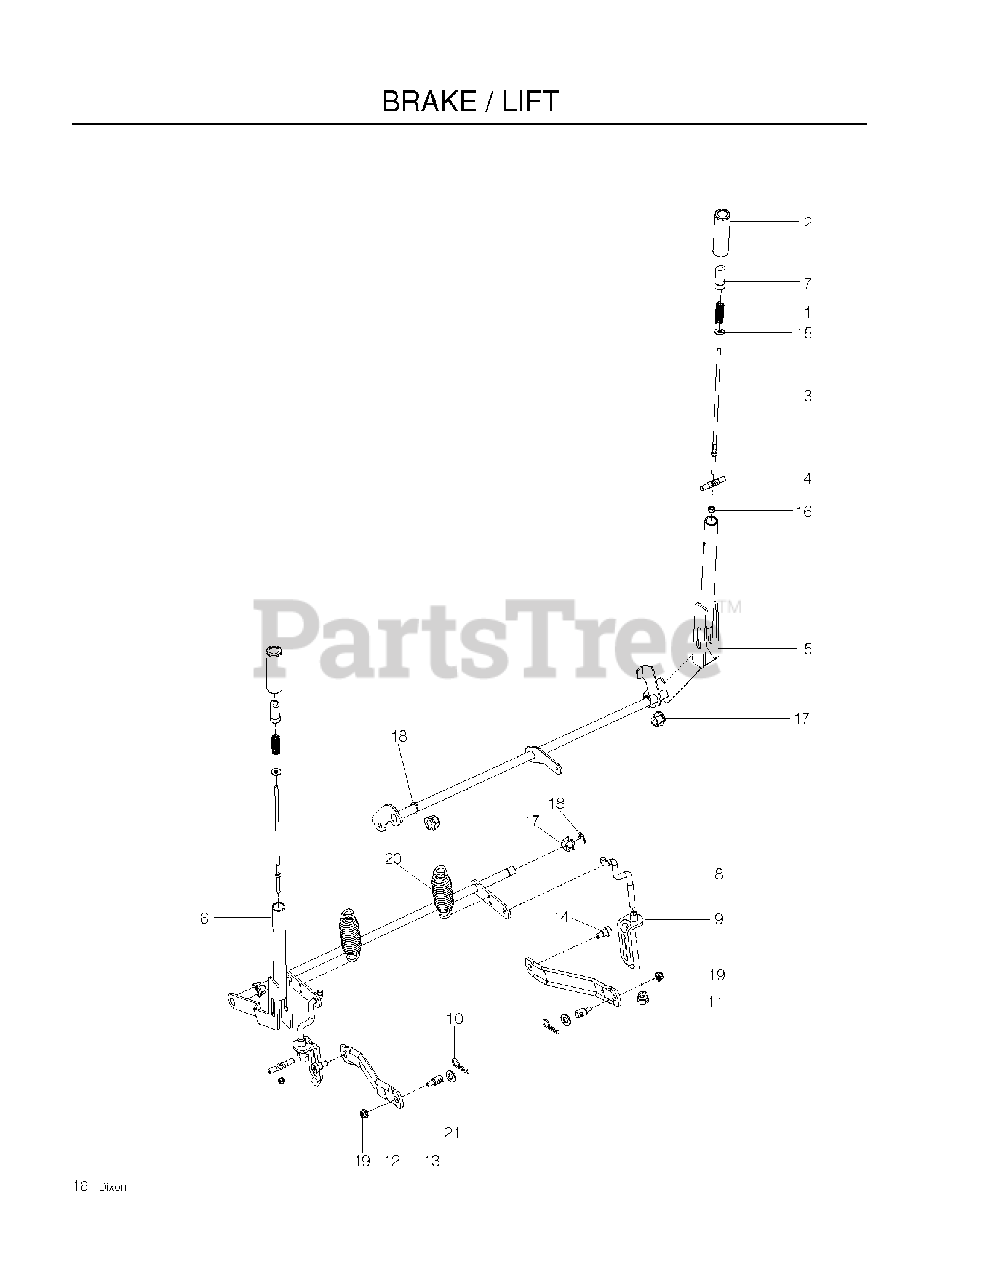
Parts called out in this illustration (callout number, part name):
1	SPRING, COMPRESSION
2	GRIP, HANDLE, BLACK
3	ROD, HANDLE RELEASE
4	ROD, LATCH RELEASE
5	SHAFT.ASSY.BRAKE.WLDMT.BLACK
7	BUTTON, PUSH, BLACK (2 2)
8	LINK, REAR SUSPENSION
9	ASSEMBLY, BRKT LINK
10	HAIRPIN #4
11	NUT, LIFT LINK 7/16-20
12	ARM.SUSPENSION.MOWER
13	STUD.FASTNER.W/ANTI-ROTATE
14	SB 3/8-16 X 3/8 SKT HD ZD
15	WASHER 1/4 FLAT
16	NUT 1/4-20 NYLOC
17	PLASTIC NUT
18	E-RING 5/8
19	5/16-18 NYLOC FLANGE NUT
21	WASHER 5/8 FLAT
